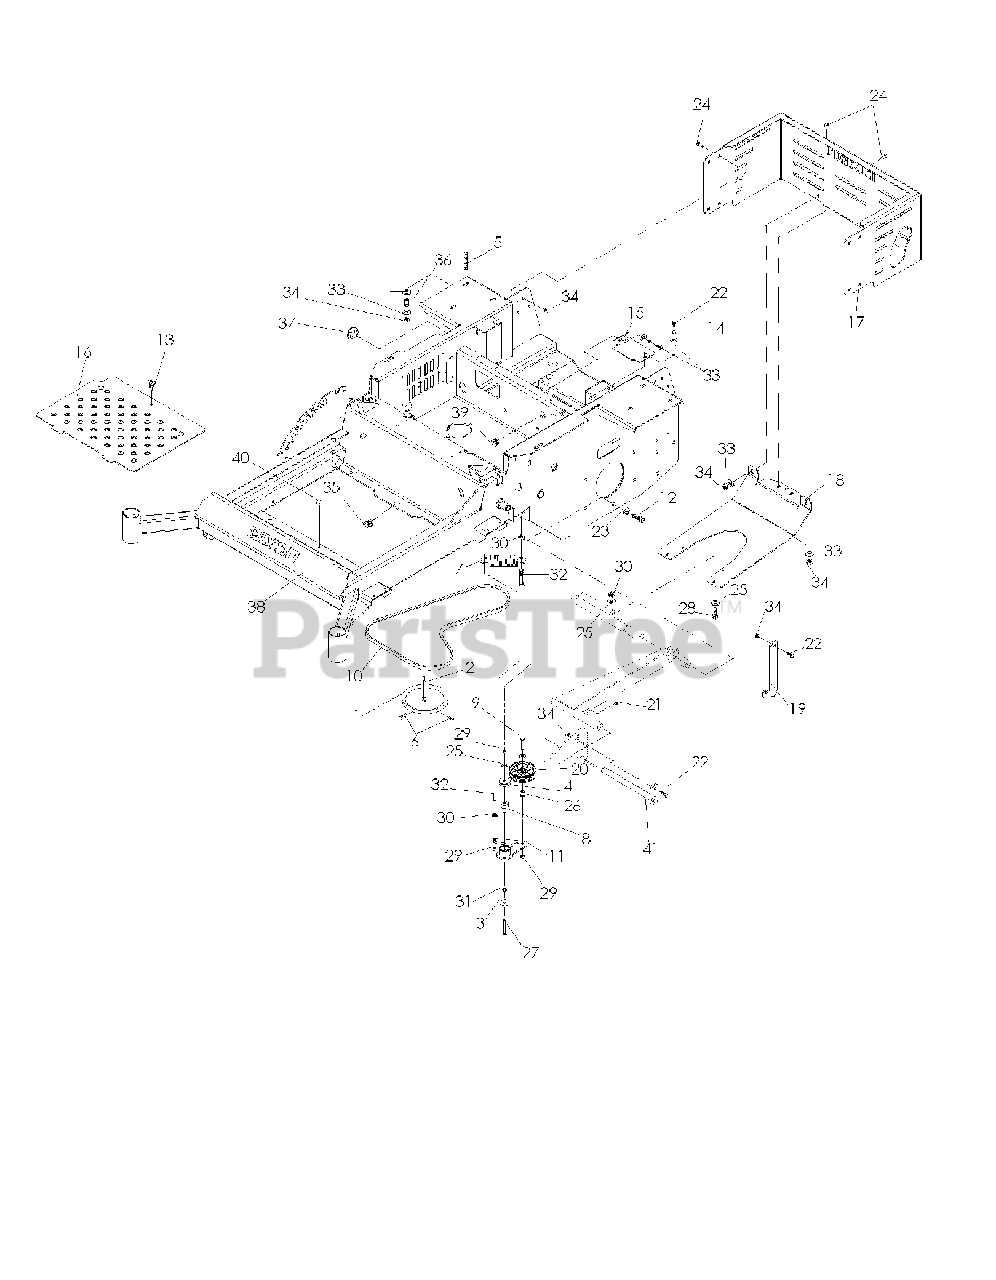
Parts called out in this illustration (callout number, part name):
2	KEY 5 MM SQ X 25 MM
3	WASHER, 3/8 SPEC
4	SHIELD, DUST
5	STUD, 5/16C
6	SCREW 5/16C X 5/8 SQ HEAD
8	PIVOT, BEARING
9	HCS 3/8C X 2
10	PUMP BELT
11	ARM, IDLER - W/BEARINGS
12	HEX SCREW 7/16-14 X 1 GR8
13	KNOB W/STUD
14	WASHER 5/16 LOCK
15	IDLER COVER
16	FLOOR PLT W/DECAL
17	GRD, REAR W/DECAL
18	PLATE, SKID
19	STOP, SEAT
20	IDLER PULLEY
21	ZERK
22	HCS 5/16C X 1
23	WASHER 7/16 LOCK
24	BOLT 5/16C X 3/4" CARRIAGE
25	WASHER 3/8 FLAT
26	BUSHING, IDLER FLANGE
27	HEX SCREW 3/8-20 X 2.75
28	HCS 3/8C X 1
29	NUT 3/8-16 NYLOC
30	NUT 3/8C WHIZ
31	WASHER 3/8 SAE FLAT
32	HCS 3/8C X 1 1/2
33	WASHER 5/16 FLAT
34	NUT 5/16 NYLOC
35	U-CLIP 5/16-18 NUT RETAINER
37	GROMMET
38	FRAME W/DECALS
39	GROMMET, FUEL LINE
40	GROMMET, BUMPER
